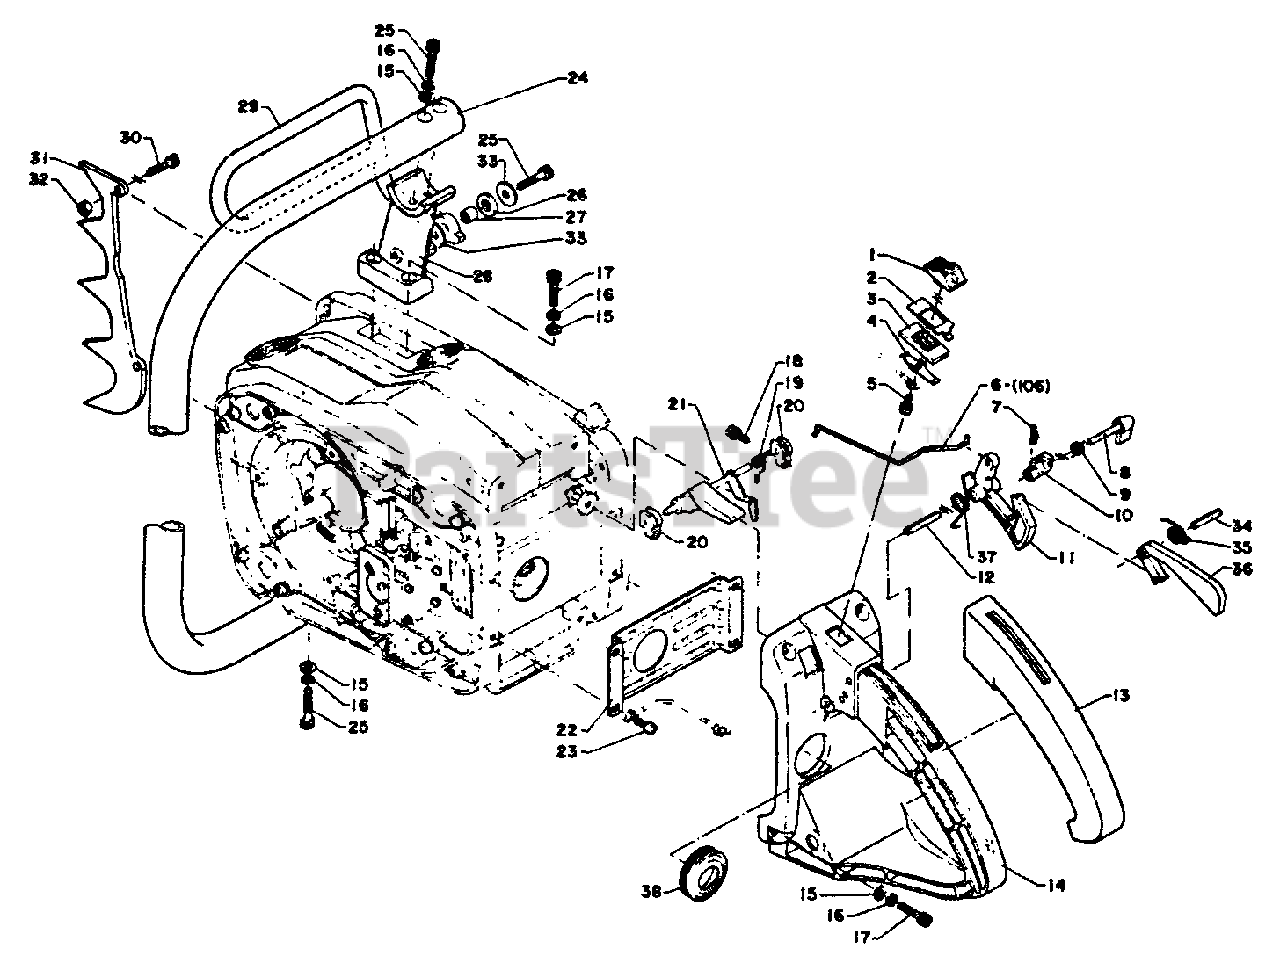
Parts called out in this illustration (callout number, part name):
1	KNOB, SWITCH
2	PLATE - GROUND
3	GUIDE, SWITCH
4	CONTACT, SWITCH
5	SCREW - 4X10
6	ROD, THROTTLE
7	PIN - LOCKING
8	LEVER, THROTTLE
9	SPRING, LOCKOUT LEVER
10	LOCKOUT, THROTTLE
11	TRIGGER, THROTTLE
12	PIN - SPRING -- 5X28
13	COVER, HANDLE
14	HANDLE - RIGHT
15	WASHER - 5
16	LOCKWASHER - 5
17	SCREW - 5X20
18	SCREW - 4X12
19	Lever spring
20	BUSHING
21	LEVER, PUMP
22	BRACKET
23	SCREW - 4X14
24	HANDLE - FRONT
25	SCREW - 5X25
26	WASHER
27	GUARD
28	Left handle support
29	GUARD
30	SCREW - 5X15
31	SPIKE
32	LOCKNUT - 5
34	PIN - SPRING -- 4X25
35	SPRING, LOCKOUT LEVER
36	LOCKOUT, THROTTLE
37	SPRING, TRIGGER
38	SEAL, DUST
